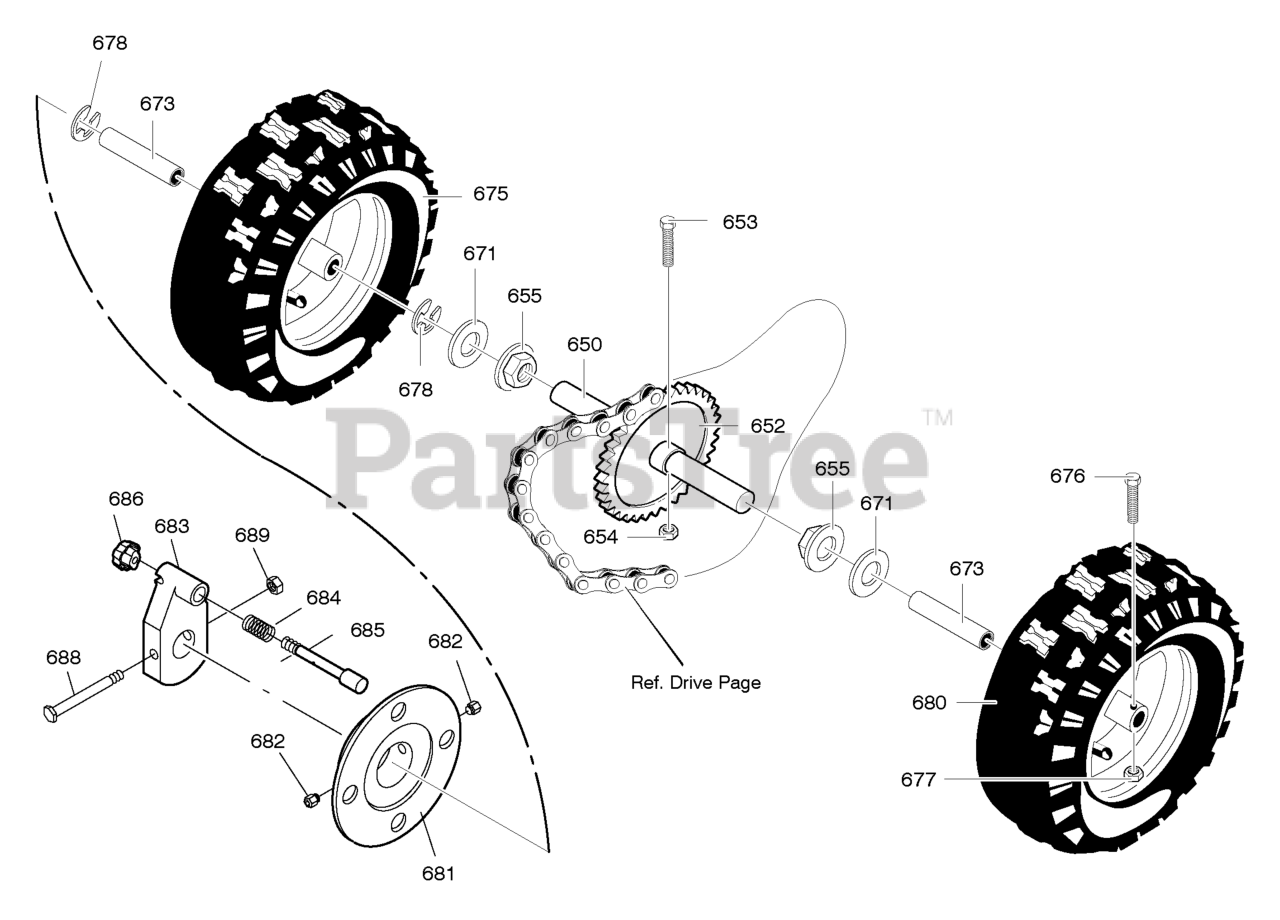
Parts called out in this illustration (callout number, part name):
650	SHAFT, AXLE
652	SPRKT & HUB
653	SCREW, 1/4-20X1.75
654	NUT, 1/4-20 HEX NYLOCK
655	BEARING, AXLE
671	FLATWASHER
673	BUSHING, WHEEL
675	TIRE & RIM, RIGHT
676	SCREW, 1/4-20X1.75
677	NUT, 1/4-20 HEX NYLOCK
678	RING, RET
680	TIRE & RIM, LEFT
681	DISC, WHEEL
683	HUB, WHEEL LOCK
684	SPRING, COMPRESSION
685	PIN, LOCK
686	KNOB
689	NUT
